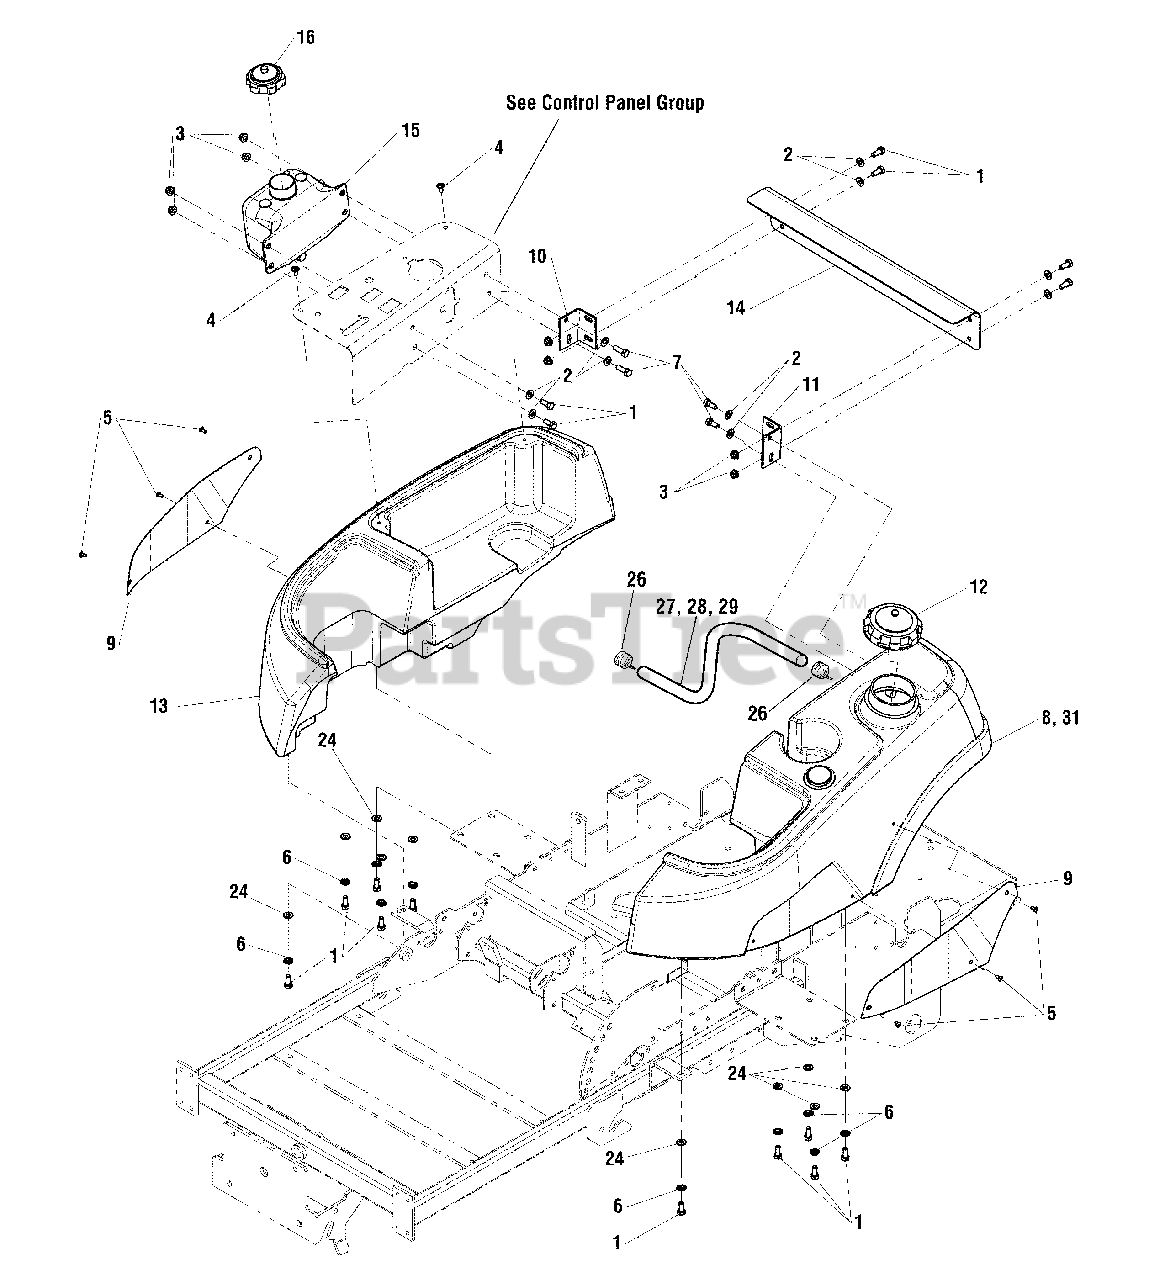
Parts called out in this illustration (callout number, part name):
1	BOLT, 5/16-18 X 3/4 GD5
2	WASHER, 5/16" SAE
3	NUT, 5/16-18 HEX NYLOCK FLANGE
4	SCREW, ALLEN HEAD, 1/4-20X1/2
5	SCREW, Allen Head, #10-24 x 3/8"
6	WASHER, 5/16" LOCK
7	BOLT, 5/16-18 X 1" GD5
8	FUEL TANK ASSEMBLY
9	PLATE, FUEL TANK BADGE - RED
10	BRACKET, REAR SUPPORT - RH - RED
11	BRACKET, REAR SUPPORT - LH - RED
12	FUEL CAP, 3.5", VENTED
13	TANK, FUEL - RH
14	PLATE, SUPPORT, REAR TANK - RED
15	TANK, 2QT HYDRAULIC
16	CAP, HYDRAULIC RESERVOIR
24	WASHER, GR. 9 FLAT
26	CLAMP, HOSE, RED
27	HOSE, 1/4" FUEL LINE, 20" LONG
28	HOSE, 1/4" FUEL, 28.00"
29	HOSE, 1/4 FUEL, 31.00
31	TANK, FUEL - LH
